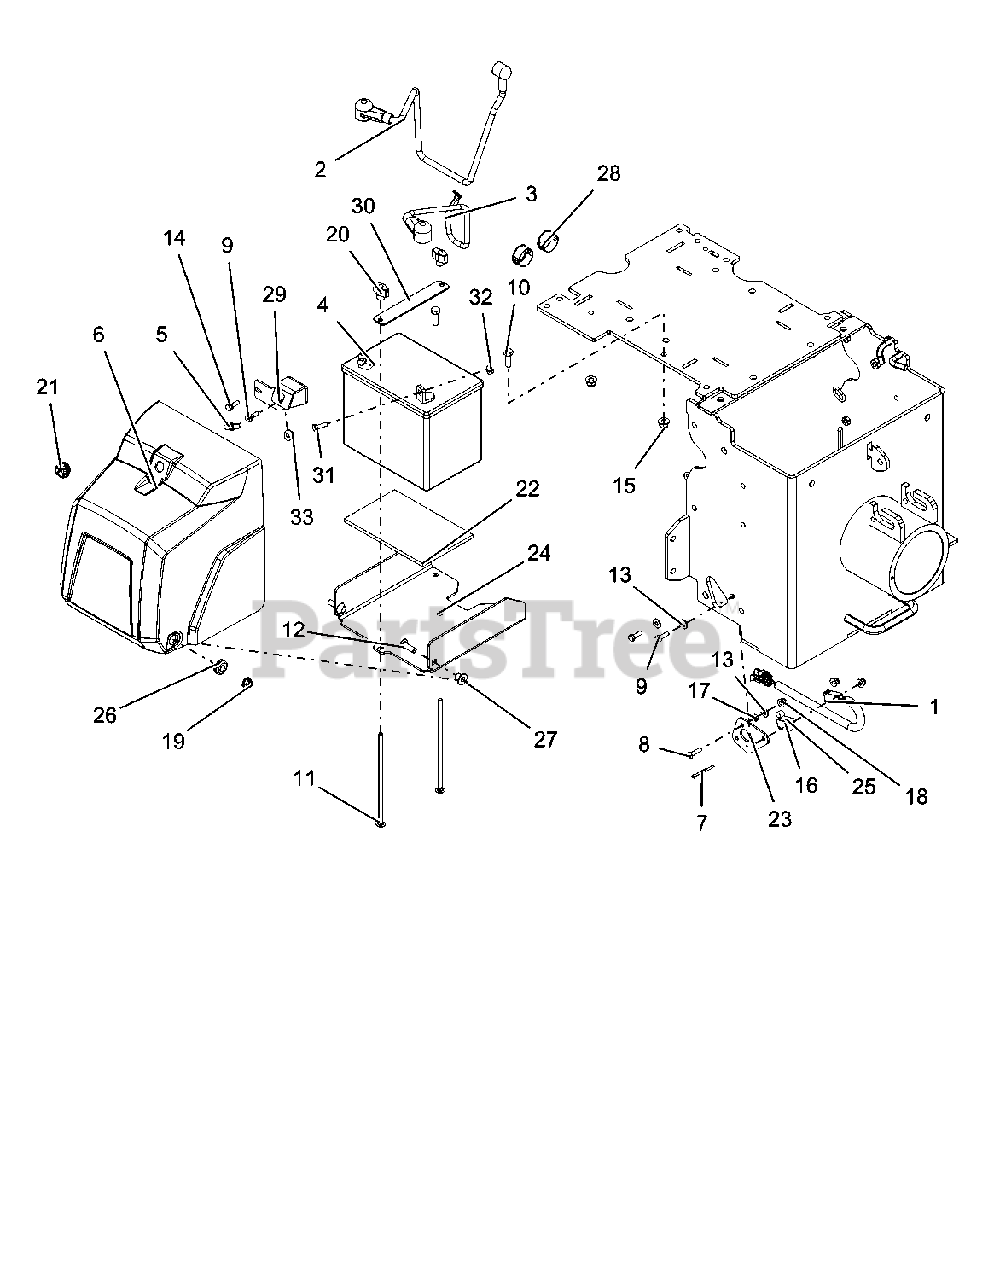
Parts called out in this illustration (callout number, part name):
1	ASM, SWITCH W/LEADS&CONNECTOR
2	CABLE, POSITIVE BATTERY 16.75"
3	CABLE, NEGATIVE BATTERY 22.5"
4	BATTERY, 300 CCA 10U1L
5	STUD-BALL
6	COVER, BATTERY
7	SCR, SKH M3-.5 X 25 GR12.9 ROHS
8	BLT, HEX M6-1X25 GR8.8 ZC120
9	BLT, HEX M6-1X20 GR8.8 ZC120
10	BLT, HEX M8-1.25X25 GR8.8 ZC120
11	BLT-RDHDSQSHNK .25-20X7.00 G2 ZC120
12	BLT-RDHDSQSHNK .31-18X1.75 GR5 ZX120
13	WSHR-FL-STL .196X.500X.06 ZC120
14	WSHR-LK .25X.062 REG YWZC
15	NUT, LK-NYL-FLG M8-1.25 GR8.8 ZC120
16	NUT, LK-NYL-FLG M3-0.5 GR8.8 ZC120
17	NUT, HEX-JAM M6-1.0 GR8.8 ZC120
18	NUT, LK-NYL-FLG M6-1.0 GR8.8 ZC120
19	NUT, LK-NYL-FLG .31-18 GR5 ZC120
20	KNOB, WING - .25-20 UNC
21	GROMMET, 10mm BOLLHOFF
22	PAD, BATTERY
23	PLATE, BASE-RED
24	SUPPORT, BATTERY-RED
25	SPRG, SWITCH
26	GROMMET, COVER MNT
27	BSHG, FRONT COVER
28	BSHG, PANEL SNAP-IN 1.25" BLK
29	BRKT, BATTERY COVER-RED
30	BAR, BATTERY STRAP-BLACK
31	BLT, HEX M6-1X20 GR8.8 ZC120
32	NUT, FLG-SPNLK M6-1.0 GR8.8 ZC120
33	NUT, LK-NYL-FLG .31-18 GR5 ZC120
